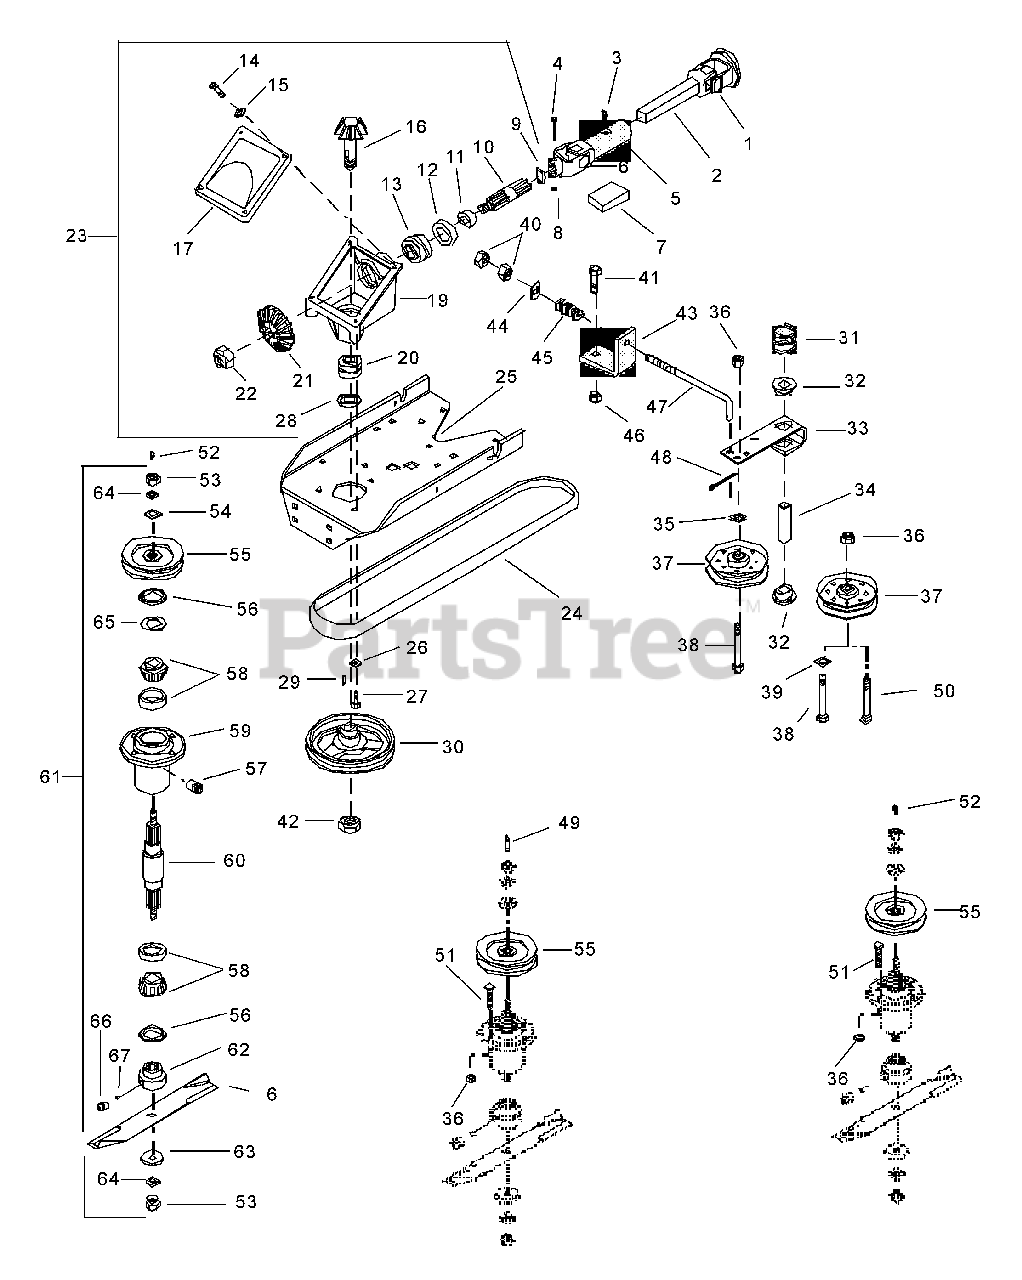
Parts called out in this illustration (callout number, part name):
1	Q.D. Yoke
2	Shaft-Prop Square Bar
3	Fitting-Lube .25-28 x .256
4	Bolt-Hex .25-20 x 2.00 Grade 5
5	Joint-U Female End
6	Blade-50" Mower
6	Blade-50" Double Edge
6	Blade-40" Mower
7	Kit-Repair U-Joint
8	Nut-Locking-Nylon .250-20 Grade 2
9	Ring-Retaining 1.106 x .95
10	Shaft
11	Bushing Flange 1.00 x 1.25 x 1.25
12	Seal 1.250 x 1.983 x .250
13	Bearing-Assembly 1.000 x 1.980 x 1.243
14	Bolt-Hex .25-20 x .50 Grade 5
15	Washer-Lock .250
16	Shaft-Pinion Gear
17	Cover-Gear Housing
19	Casting-Gear Box
20	Bearing-Assembly .75 x 1.781 x 1.499
21	Gear-Bevel
22	Nut-Locking-Nylon .75-10 Grade 2
23	Assembly-Gearbox
24	V-Belt A-Section
24	Belt-V
25	Support-Gear Housing
26	Washer-Lock .50 Regular
27	Bolt-Hex .50-13 x 1 Grade 5
28	Seal 1.250 x 1.691 x .310
29	Key-Woodruff .19 x .63
30	Sheave 1/2 x 6.50
31	Spring-Compression .085 x .80 x 1.00
32	Bushing-Flange .762 x 1.0 x .580 x 1.48
33	Arm-Idler Pivot
34	Spacer .560 x .750 x 2.437 Steel
35	Bushing .406 x .750 x .188
36	Nut-Locking-Nylon .375-16 Grade 2
37	Pulley-Idler 4.50 x .380
38	Bolt-Hex .38-16 x 2.00 Grade 5
39	Washer-Flat-Steel .438 x 1.000 x .083
40	Nut-Hex .375-24 Grade 2
41	Bolt-Hex .50-13 x 1.50
41	Bolt-Hex .50-13 x 1.375
42	Nut-Hex-Jam .750-10
43	Support-Spring
44	Washer-Flat-Steel .406 x .812 x .065
45	Spring-Compression .125 x .78 x 1.00
46	Nut-Locking-Nylon .50-13 Grade 5
47	Rod, Idler 50 In. Mower
47	Rod, Idler 40 In. Mower
48	Pin-Cotter .09 x 1.0
49	Fitting-Lube .125
50	Bolt-Round Head Square Neck .38-16 x 1.75
51	Bolt-Round Head Square Neck .38-16 x 1.25
52	Fitting-Lube 1/8
53	Nut-Hex .625-11 Grade 2
53	Nut-Locking-Nylon .625-11 Grade 2
54	Washer-Flat-Steel .687 x 1.312 x .150
55	Sheave
56	Seal 1.987 x 1.375 x .313
57	Relief Fitting-Grease
58	Assembly, Bearing Cup & Cone
59	Bearing Housing
60	Shaft, Spindle
61	Service Kit Spindle Assembly
62	Hub
63	Washer
63	Washer-Flat-Steel .656 x 1.312 x .095
64	Washer-Locking .625 x .156
65	Washer-Flat-Steel 1.007 x 1.542 x .062
66	Screw-Set .25-20 x .25
67	Plug
